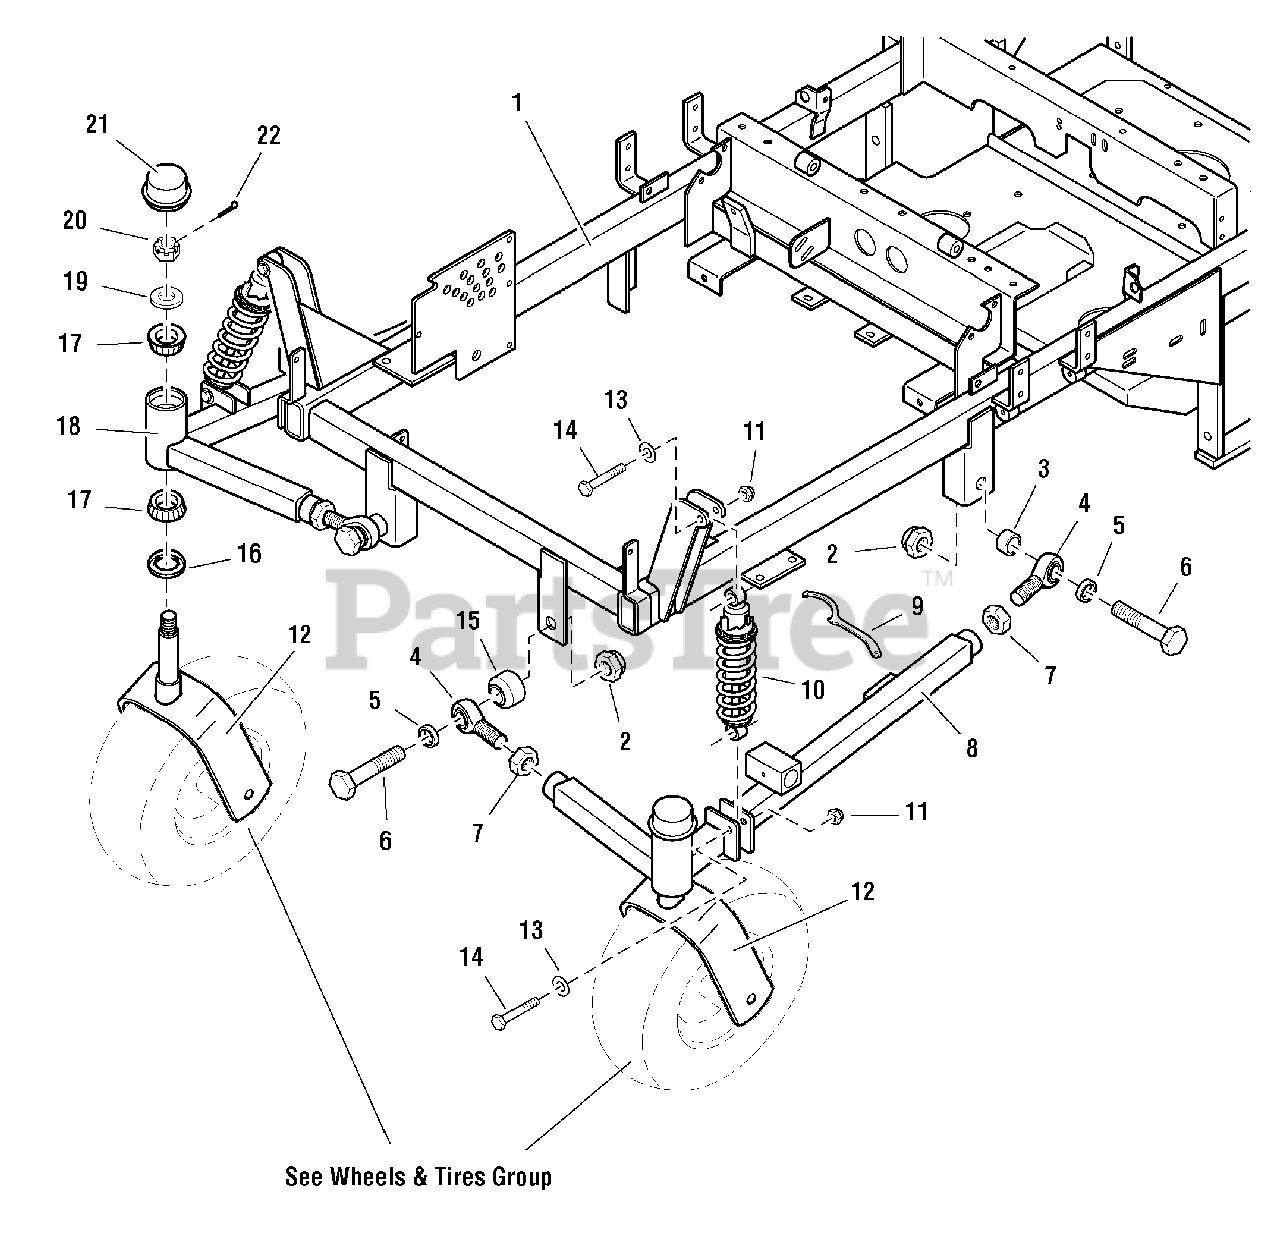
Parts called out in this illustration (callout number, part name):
1	* MAIN FRAME
2	NUT, Hex, Nylon Lock, 3/4-16
3	SPACER, .76 x 1.00 x .50
4	BALL JOINT, 3/4-16
5	SPACER, .76 x 1.00 x .25
6	CAPSCREW, Hex Hd, 3/4-16 x 3-1/2
7	NUT, Hex, Jam, 3/4-16
8	SUSPENSION ARM - LH
9	SPANNER WRENCH
10	SHOCK & SPRING ASSEMBLY
11	NUT, Hex, Nylon Lock, 3/8-16
12	CASTER TIRE MOUNT
13	WASHER, 3/8
14	CAPSCREW, Hex Hd, 3/8-16 x 2-1/4
15	SPACER, .75 x 1.50 x 1.00
16	GREASE SEAL
17	BEARING, Tapered Roller
18	SUSPENSION ARM - RH
19	WASHER, 3/4
20	NUT, Hex, Slotted, 3/4-16
